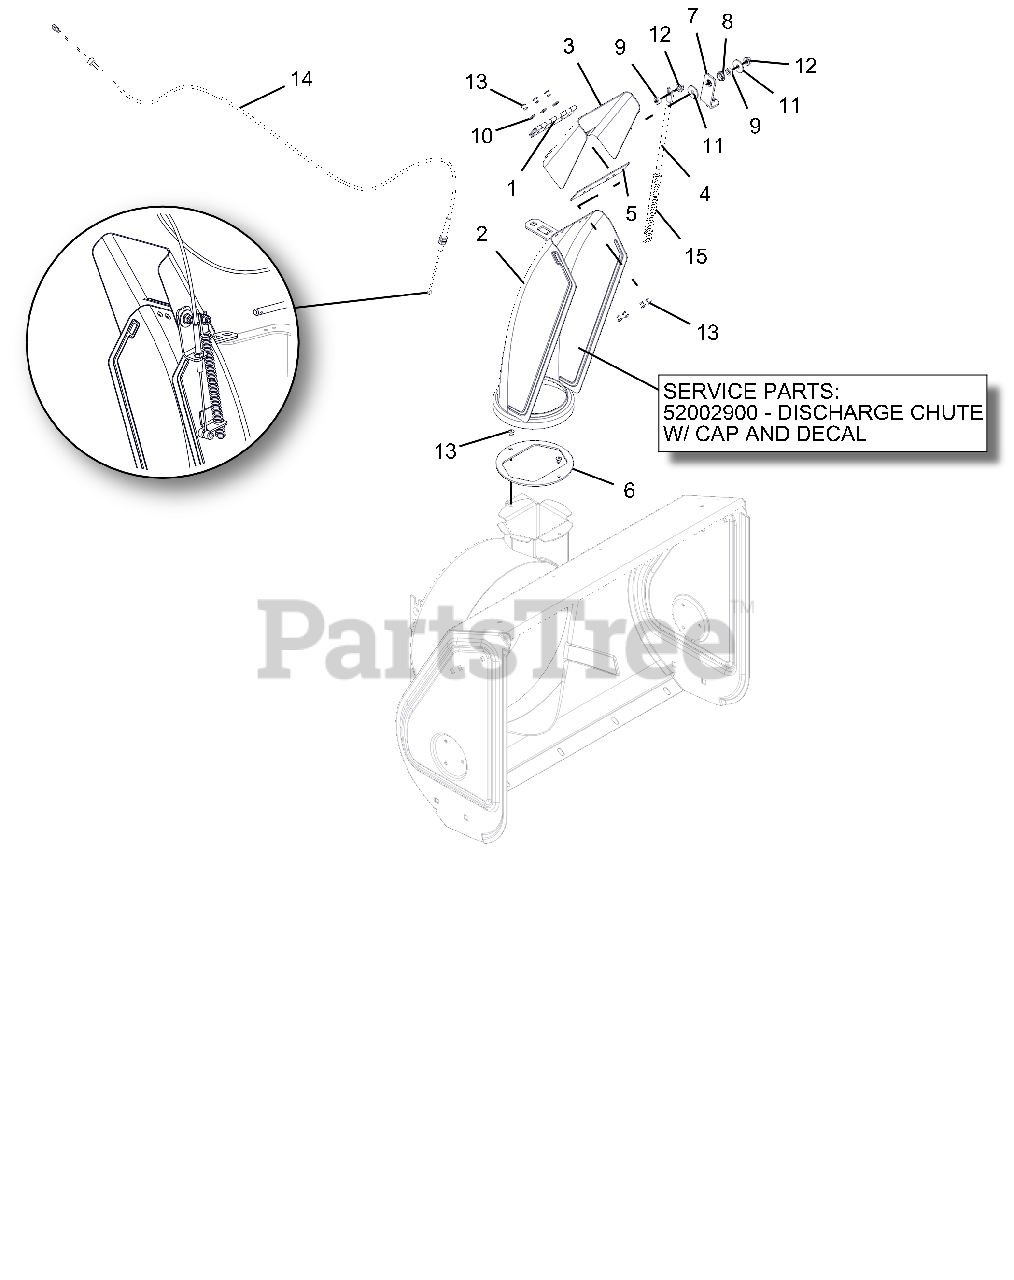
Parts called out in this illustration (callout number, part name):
2	CHUTE, COMPACT-TALL W/REMOTE
2	CHUTE, DISCHARGE W/REM.CAP,DEC
3	CAP, COMPACT-W/REMOTE
4	ROD, DEFLECTOR CAP
5	CAP SEAL 5.25
6	BAFFLE, COMPACT DISCHARGE
7	BRACKET, CABLE ANCHOR
8	BUSHING, POLYLINER-.50 SNAPIN
9	BSHG-SLV .265X.500X.219
10	WSHR-FL-STL .196X.500X.06 YZ
11	WSHR-FL-STL .281X1.000X.063
12	@NUT-LK-TOP-FLG .25-20 YWZC
13	RVT-POP .187 YZ
14	CABLE, DEFLECTOR - COMPACT
15	SG-COMP .08X.40X6.50 14#/IN
